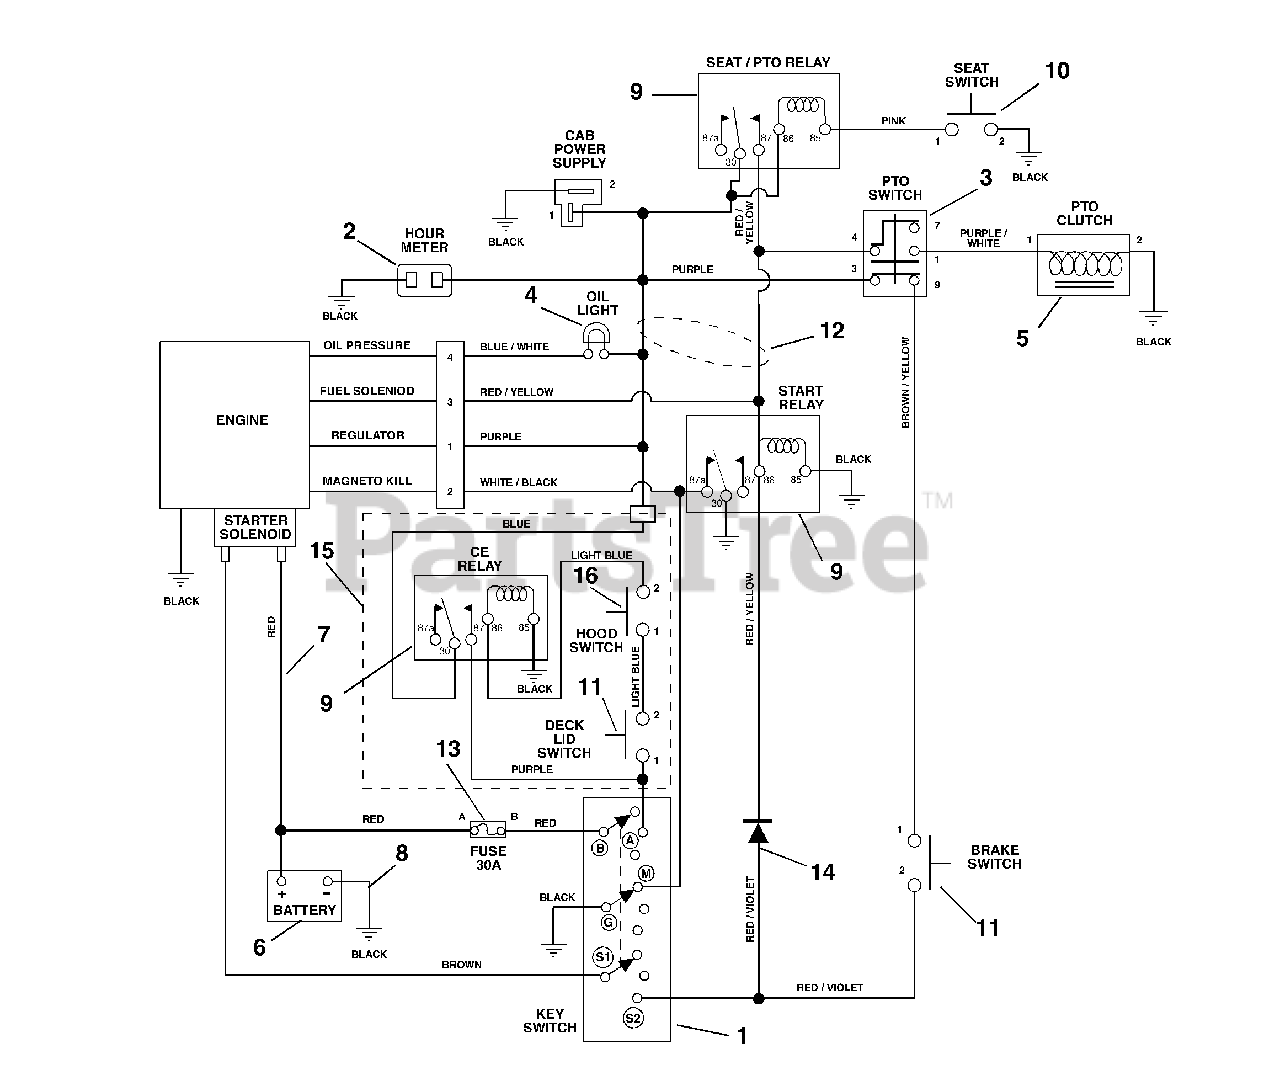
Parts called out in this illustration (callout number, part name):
1	Key Switch
2	Hour Meter
3	Switch-Clutch With Retainer Ring
4	Light-Indicator
5	Electric Clutch
6	Battery with Tube
7	Cable-Battery To Solenoid
8	Ground Cable
9	Relay
10	Seat Switch
11	Switch-Single Pole
12	Harness-Kohler
13	Fuse, 30 Amp
14	Molded Diode Plug-Black 1-Amp
15	Harness-CE Adapter
16	Switch-Single Pole (N.O.) with Cover
